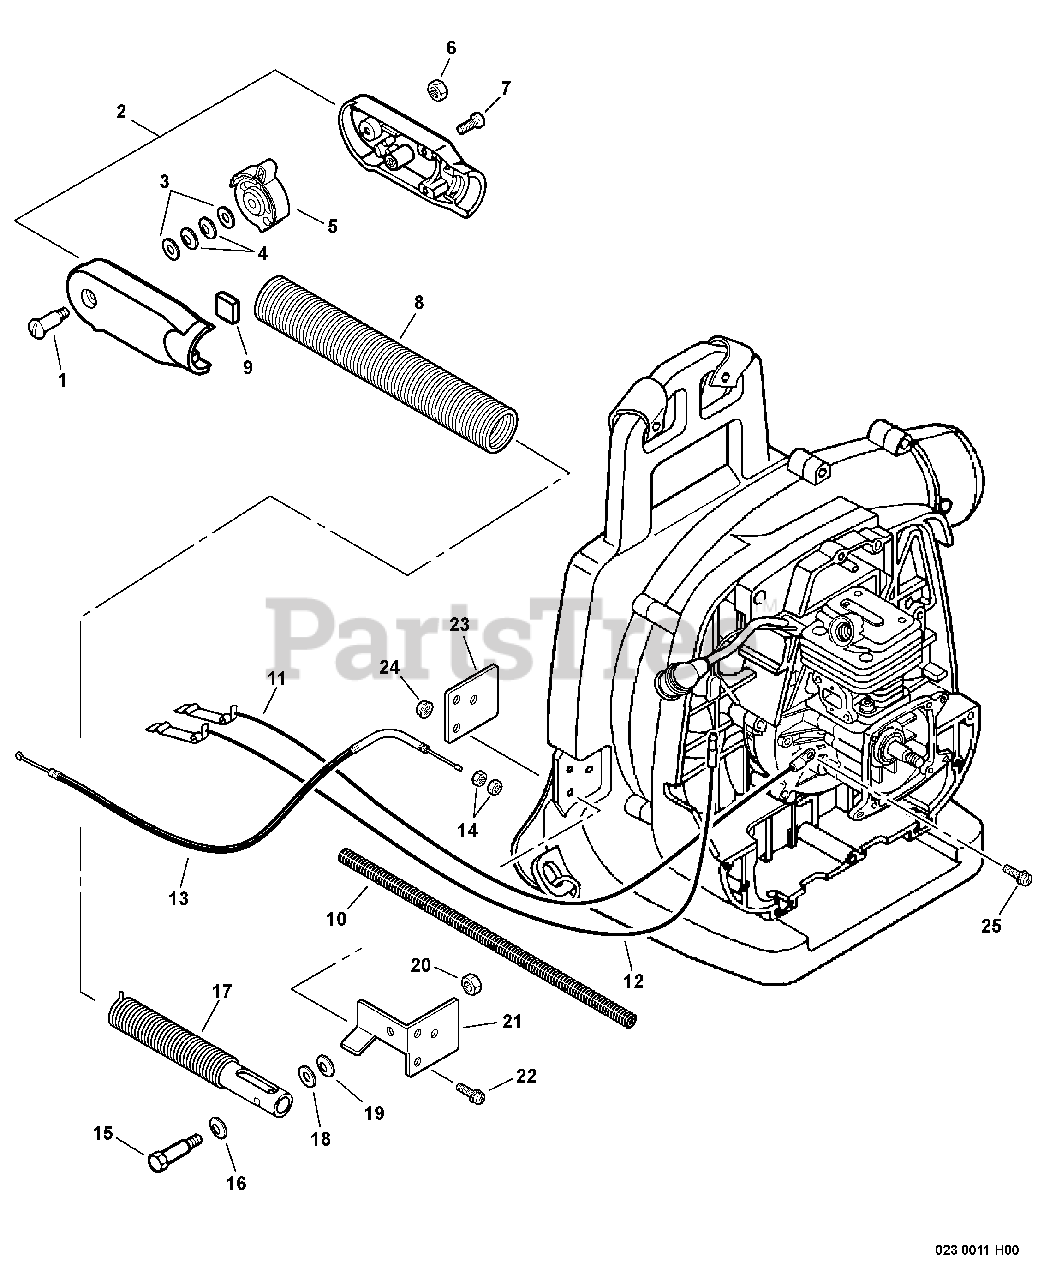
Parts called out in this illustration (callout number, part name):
2	GRIP ASSY, THROTTLE
3	WASHER 6.5×15.5×0.6
4	WASHER, FRICTION 6.6×14.3
5	LEVER, THROTTLE
6	NUT, LOCK 4
8	TUBE, OUTER FLEX
9	PAD, FOAM
10	TUBE, PROTECTIVE - CORRUGATED
11	LEAD - GROUND
12	LEAD - IGNITION
13	CABLE, THROTTLE
16	WASHER, WAVE
17	TUBE, SPRING
18	WASHER 8
19	WASHER - 8
21	BRACKET, MOUNTING
22	SCREW 5×16
24	NUT, FLANGE M5
25	SCREW 5×10
